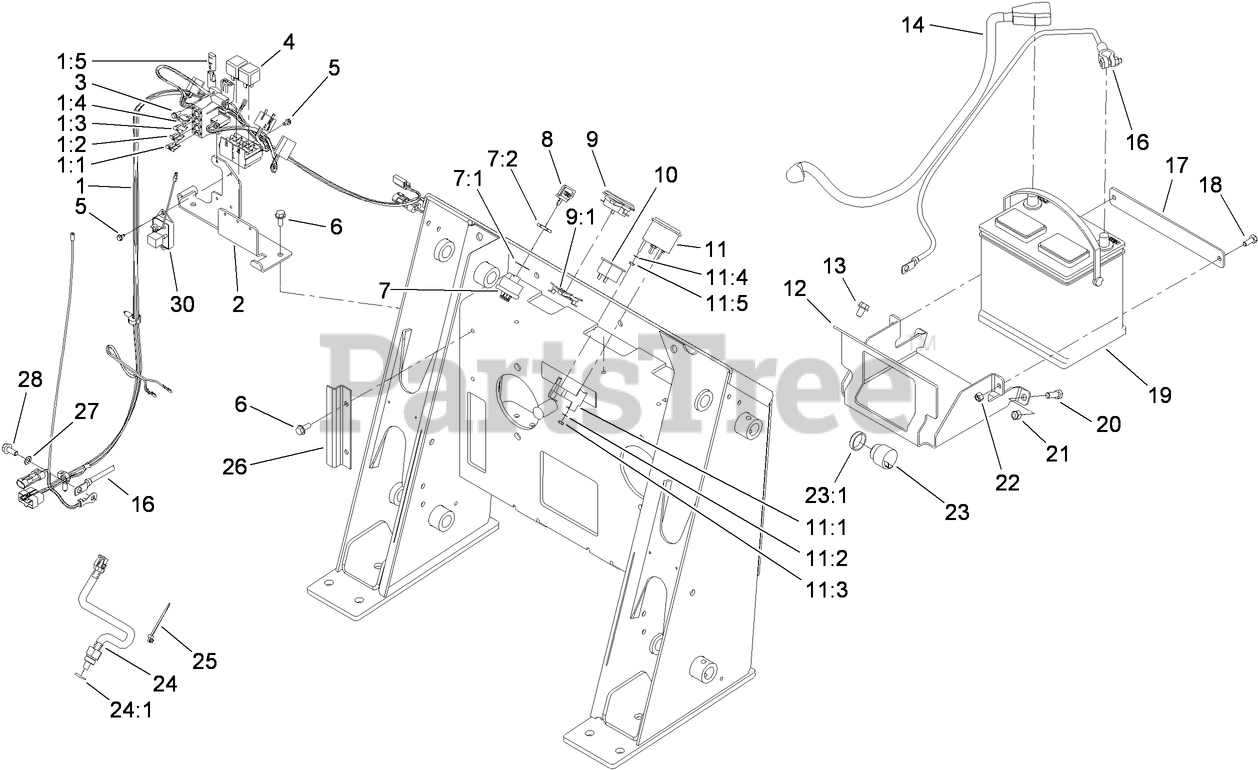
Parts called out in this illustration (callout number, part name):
1	HARNESS-WIRE
1:1	FUSE-BLADE, 30 AMP
1:2	FUSE-BLADE, 25 AMP
1:3	FUSE-BLADE, 10 AMP
1:4	FUSE-BLADE, 15 AMP
1:5	CAP-PLUG
2	BRACKET-FUSE/RELAY
3	SCREW-HWH
4	RELAY
5	SCREW-HWH
6	SCREW-HWHTF
7	Key Switch ASM
7:1	WASHER-TOOTH, INTERNAL
7:2	NUT-HH
8	KEY-IGNITION
9	INDUCTIVE HOURMETER ASM
9:1	CLIP-MOUNTING
10	LIGHT-TEMP, OIL
11	GAUGE-FUEL
11:1	BRACKET-MOUNTING, GAUGE
11:2	WASHER-LOCK, INT
11:3	NUT-HEX
11:4	WASHER-LOCK / EXT
11:5	NUT-HEX
12	TRAY-MOUNTING, BATTERY
13	SCREW-HWHTF
14	CABLE-BATTERY, POSITIVE
16	CABLE-BATTERY, NEGATIVE
17	CLAMP-BATTERY
18	SCREW-HH
19	BATTERY
20	SCREW-HH
21	NUT-LOCK, NI
22	NUT-LOCK, NI
23	AUDIO ALARM ASM
23:1	NUT-PLASTIC, KNURLED
24	SENSOR-TEMPERATURE
24:1	O-RING
25	TIE-CABLE
26	SHIELD-WIRING
27	WASHER-LOCK
28	SCREW-HHF
30	MODULE-IGNITION DELAY
